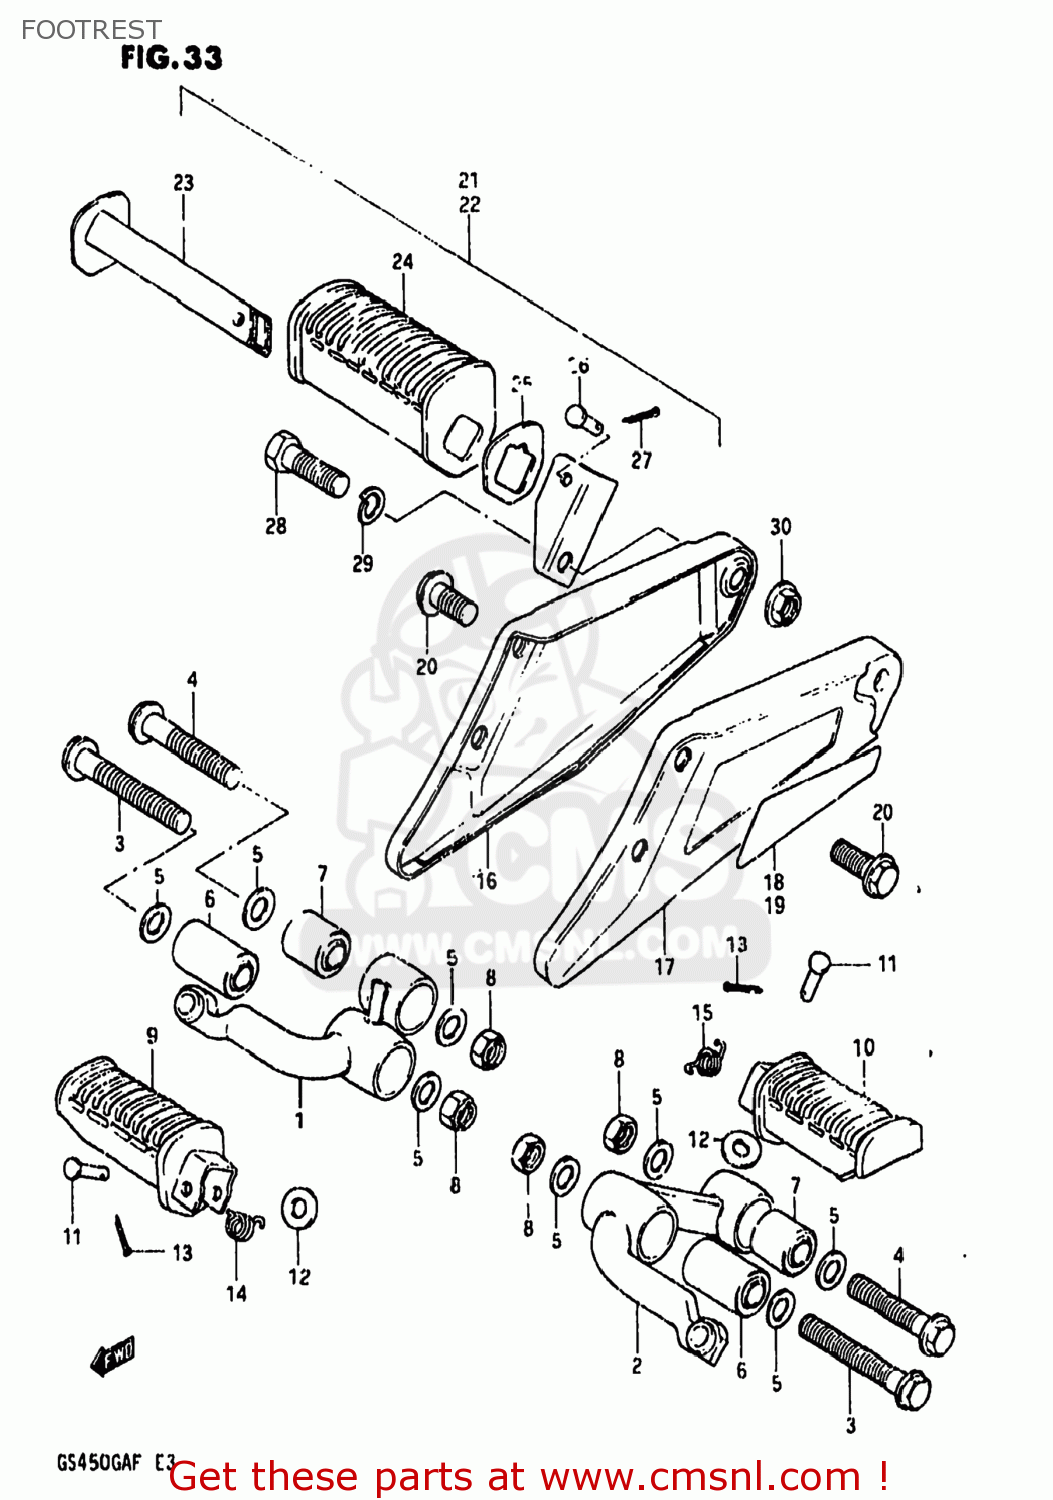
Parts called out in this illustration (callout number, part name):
1	BAR,FRONT FOOTREST
2	BAR,FRONT FOOTREST,LEFT
3	BOLT
4	BOLT
5	WASHER
6	BUSHING(10X23X35)
7	BUSH
8	NUT
9	RUBBER,FOOTREST
10	FOOTREST
11	PIN
12	WASHER
13	PIN 20X20
14	SPRING
15	SPRING
16	BRACKET
17	BRACKET
20	BOLT 10X25
21	FOOTREST ASSEMBLY,REAR,RIGHT
22	FOOTREST ASSEMBLY,REAR,LEFT
23	BAR,REAR FOOTREST,LEFT
24	RUBBER,REAR FOOTREST
25	WASHER,RR FOOTREST RUBBER
26	PIN
27	PIN 20X20
28	BOLT,M10X1.25X
29	LOCK WASHER
30	NUT
